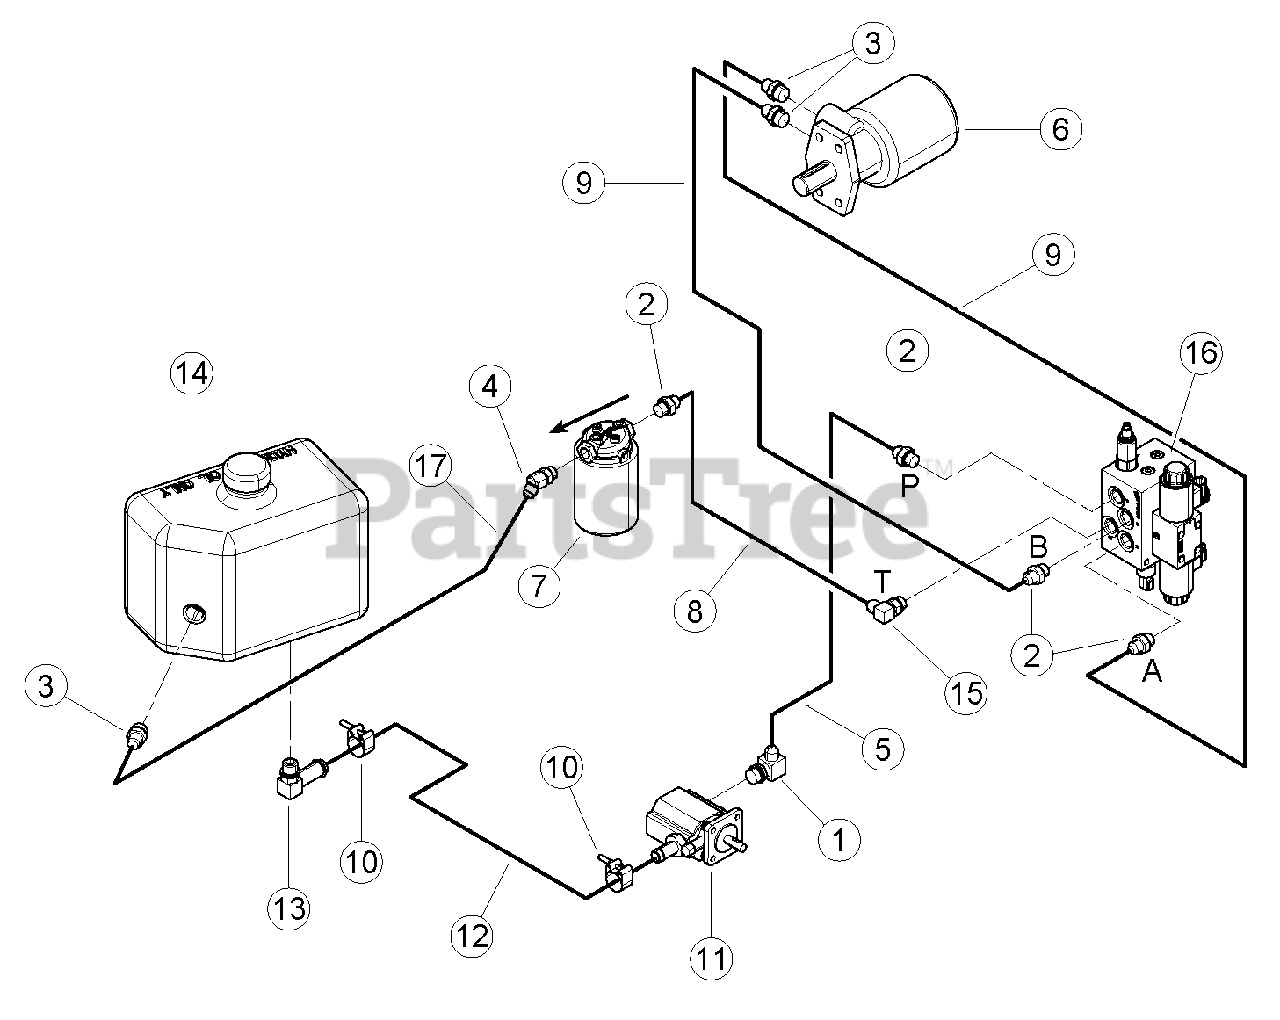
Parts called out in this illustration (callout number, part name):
1	ADAPTER, -10 MORING / -8 MJIC 90 DEG.
2	ADAPTER, -8 MORING / -8 MJIC
3	ADAPTER, -10 MORING / -8 MJIC
4	ADAPTER, -8 MORING / -8 MJIC 45 DEG.
5	HOSE ASSEMBLY, -8 FMJIC / -8 FMJICSW X 8-1/2
6	MOTOR, 45 CU. IN. HYDRAULIC
7	FILTER, SPIN ON (ARROW ON TOP OF FILTER HEAD INDICATES DIRECTION OF FLOW)
8	HOSE ASSEMBLY, -8 FMJIC / -8 FMJIC 90 X 21 INCH
9	HOSE ASSEMBLY, -8 FMJIC / -8 FMJIC 90 X 61 INCH
10	CLAMP, 1 INCH OD. HOSE T-BOLT
11	PUMP, 2 STAGE CW HI/LO 0.605 DISP.
12	HOSE, .75 ID X 28 IN 100R4 HYD
13	ADAPTER, -10 MORING/.75 90 DEG. HOSE
14	TANK, OIL RESERVOIR
15	ADAPTER, -8 MORING / -8 MJIC 90 DEG.
16	ASSEMBLY, HYDRAULIC FEED FLOW VALVE
17	HOSE, 3/8 X 35 -8 FJICSW
